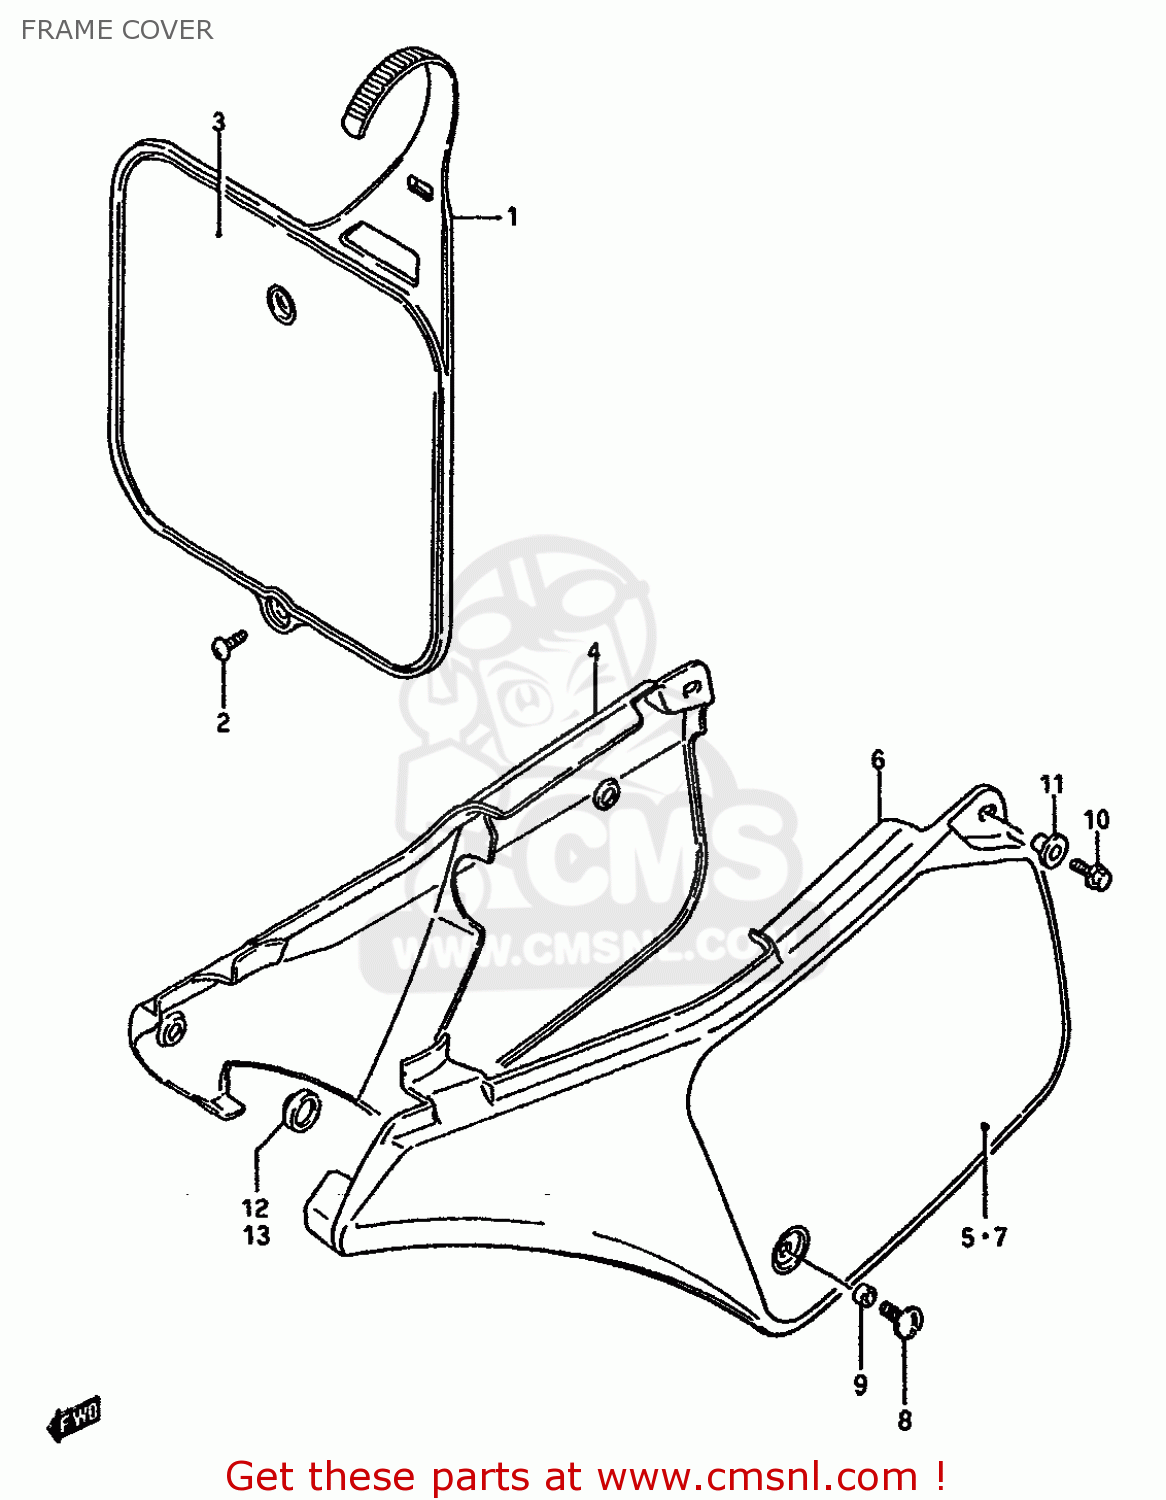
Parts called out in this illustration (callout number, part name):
1	PLATE,NUMBER,FRONT
2	SCREW
3	TAPE,FRONT NUMBER PLATE
4	COVER,FRAME,RIGHT
5	EMBLEM,FRAME COVER,NUMBER PLATE
6	COVER,FRAME,LEFT
7	EMBLEM,FRAME COVER,NUMBER PLATE
8	SCREW(6X14)
9	SPACER (6.1X8X3.5)
10	BOLT
11	WASHER
12	CUSHION
13	CUSHION
